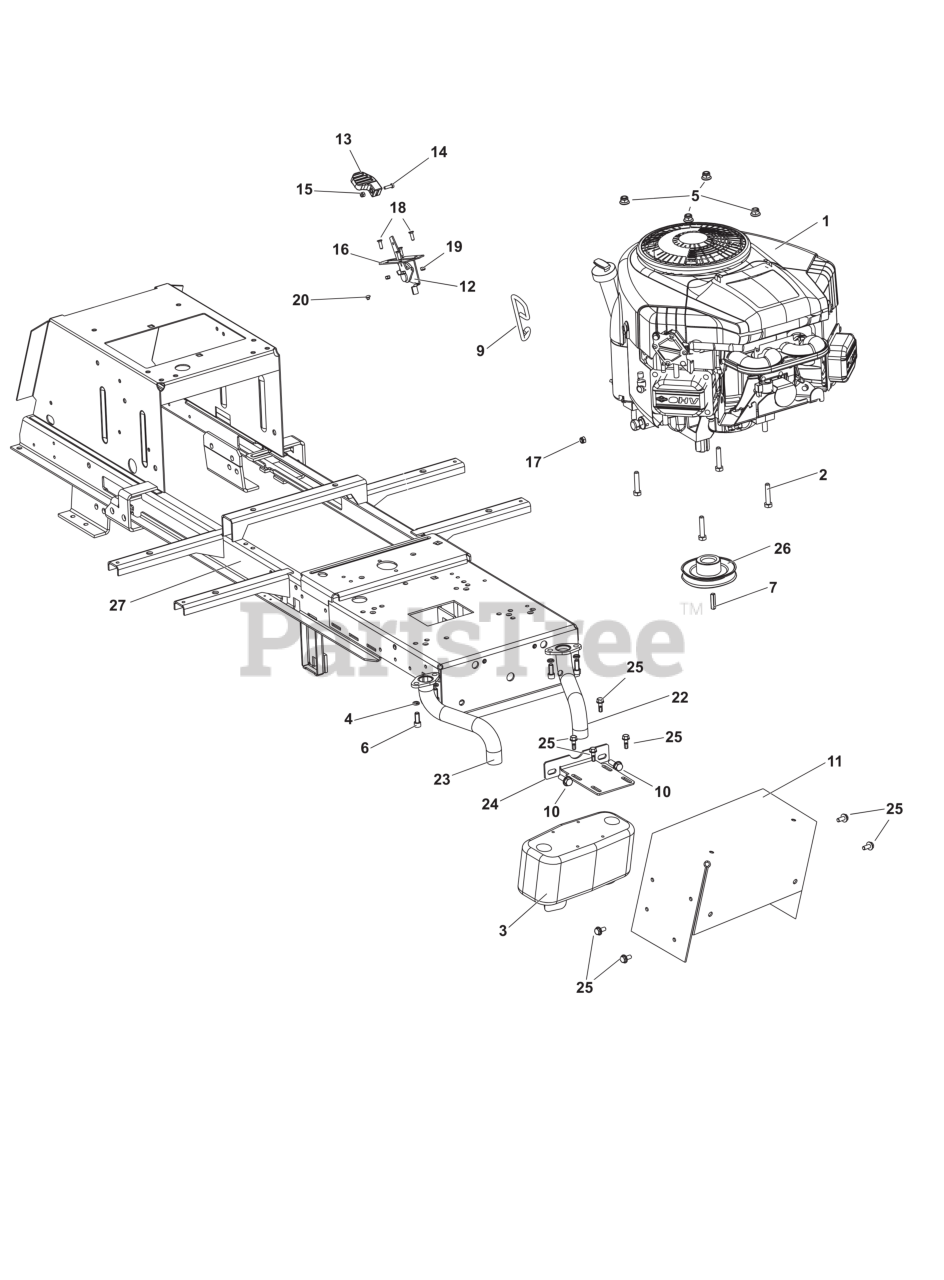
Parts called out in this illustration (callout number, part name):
1	ENGINE, B&S Twin
7	KEY, Drive Pulley
12	LEVER, THROTTLE
13	LEVER, THROTTLE
16	PLATE, Reinforcement
